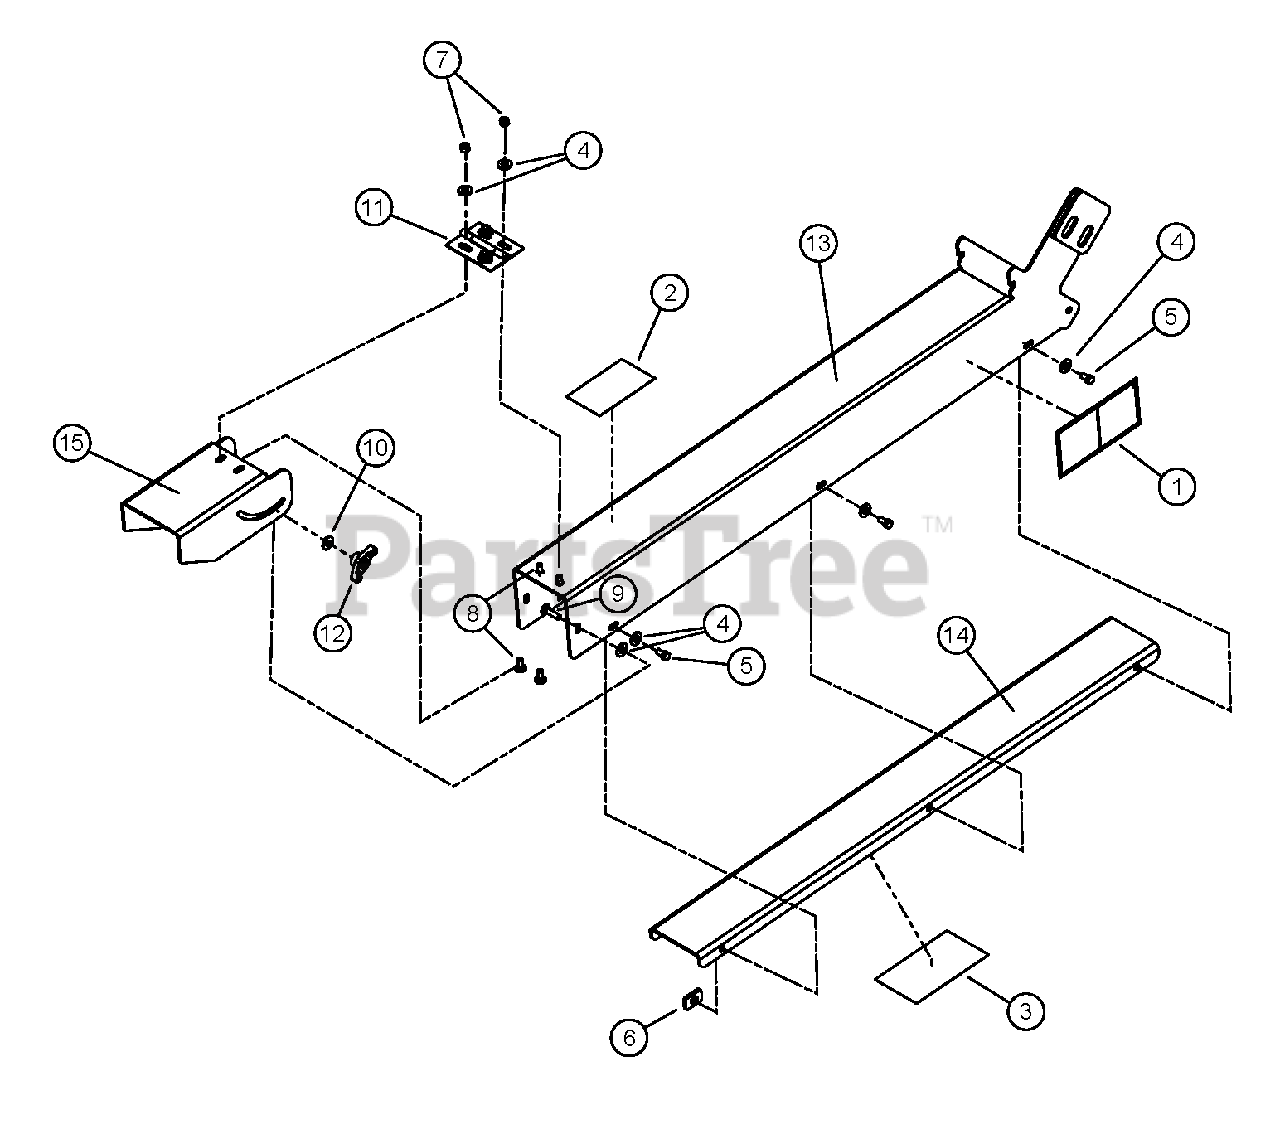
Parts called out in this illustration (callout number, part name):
1	DECAL, KNIFE ACCESS
2	DECAL, DISCHARGE
3	DECAL, INLET AND DISCHARGE
4	WASHER, 5/16" FLAT ZP
5	BOLT, 5/16" X 5/8" HHCS GR5 ZP
6	WASHER, 5/16" ID, 7/8" OD NYLON FLAT
7	NUT, 5/16" NE NYLOCK ZP
8	BOLT, 5/16" X 3/4" CARRIAGE NC GR5 ZP
9	BOLT, 5/16" X 1-1/4" CARRIAGE GR5 ZP
10	WASHER, 5/16 NYLON
11	HINGE, DISCHARGE CAP
12	KNOB, 5/16-18 UNC TEE WITH LOCKING INSERT
13	WELDMENT, CHIPPER DISCHARGE
14	WELDMENT, TOP DISCHARGE CHUTE
15	CAP, DISCHARGE
